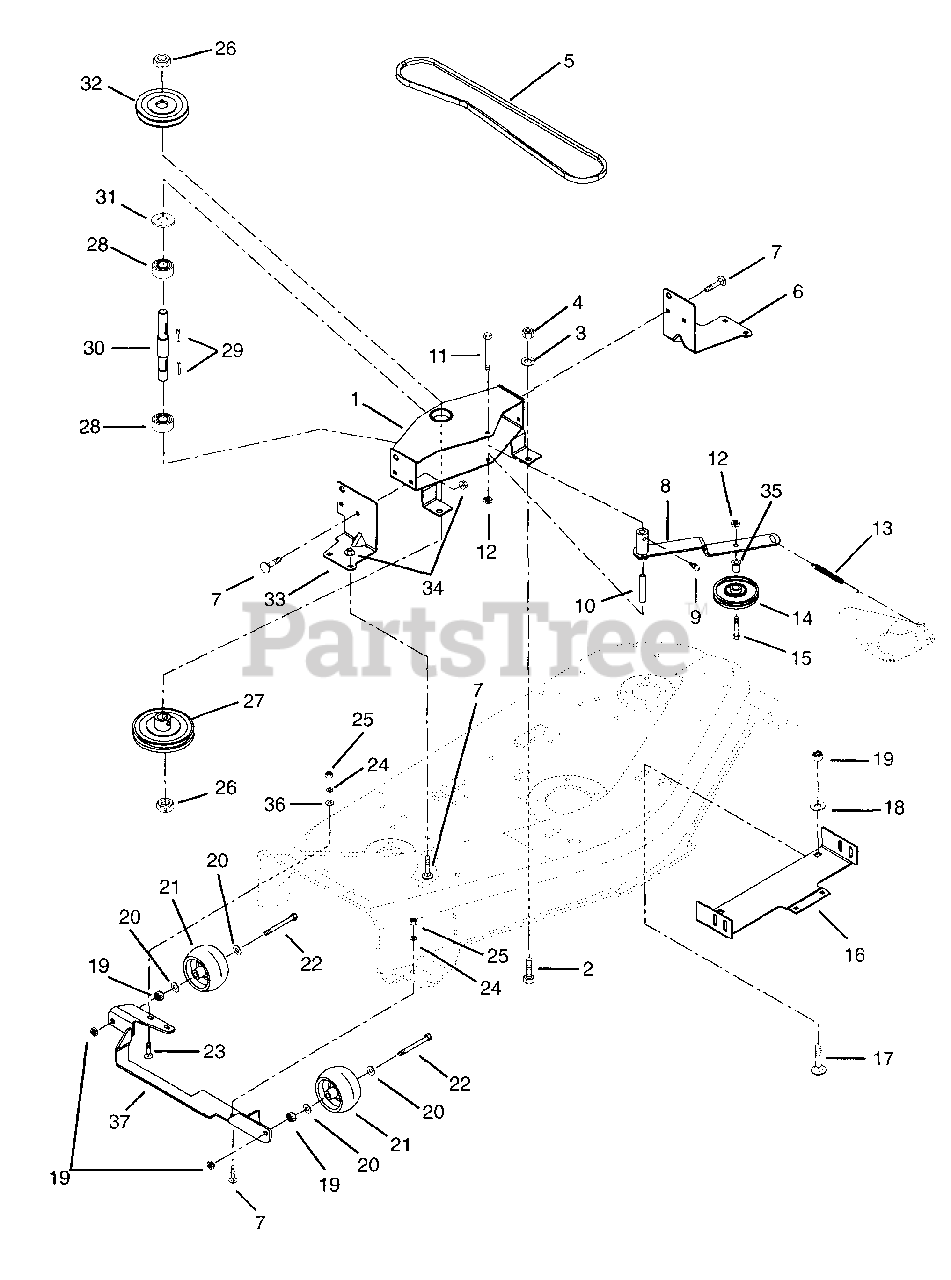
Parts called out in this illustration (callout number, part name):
1	HOUSING, JACKSHAFT
2	@BLT-HEX .50-13X1.00 GR5 YWZC
3	@WSHR-LK .50X.125 REG YWZC
4	@NUT-HEX .50-13 YWZC
5	V-BELT, 5L-RAW EDGE
6	BRACE, LEFT REAR
7	BLT-RDHDSQSHK.31-18X.75 GR2 YW
8	ARM, IDLER
9	FTG-LUBE .25-28X.256 YWZC
10	SPACER .334X.500X2.73
11	@BLT-HEX .31-18X3.50 GR5 YWZC
12	@NUT-LK-CTR .38-16 YWZC
13	SG-TENS .113X.812X7.00
14	IDLER, PLASTIC, 4.00 X .50 ID
15	@BLT-HEX .38-16X1.50 GR5 YWZC
16	BRACE, FRONT
17	@BLT-RDHDSQNK .50-13X.75 G5YZ
18	WSHR-FL-STL .505X.880X.072 YWZ
19	@NUT-LK-CTR .50-13 YWZC
20	WSHR-FL-NYL .518X1.000X.080
21	WHEEL 5 X 3
22	@BLT-HEX .50-13X4.50 GR5 YWZC
23	BLT-RDHDSQNK .31-18X1.0 SHTYZ
24	WSHR-LK .312X.097 HVY YWZC
25	@NUT-HEX .31-18 YWZC
26	@NUT-LK-CTR .75-10 YWZC
27	PLY-V 6.00 X .75 W/KEY
28	BRG-BALL .750X1.781X.61
29	KEY-SQ .187 X .50 X .187
30	JACKSHAFT
31	WSHR-FL-STL .755X1.25X.125 YZ
33	BRACE, RIGHT REAR
34	@NUT-LK-CTR .31-18 YWZC
35	SPACER -FLANGED .390X.500X.781
36	WSHR-FL-STL .38X.875X.083 PL
37	MOUNT - ROLLER
